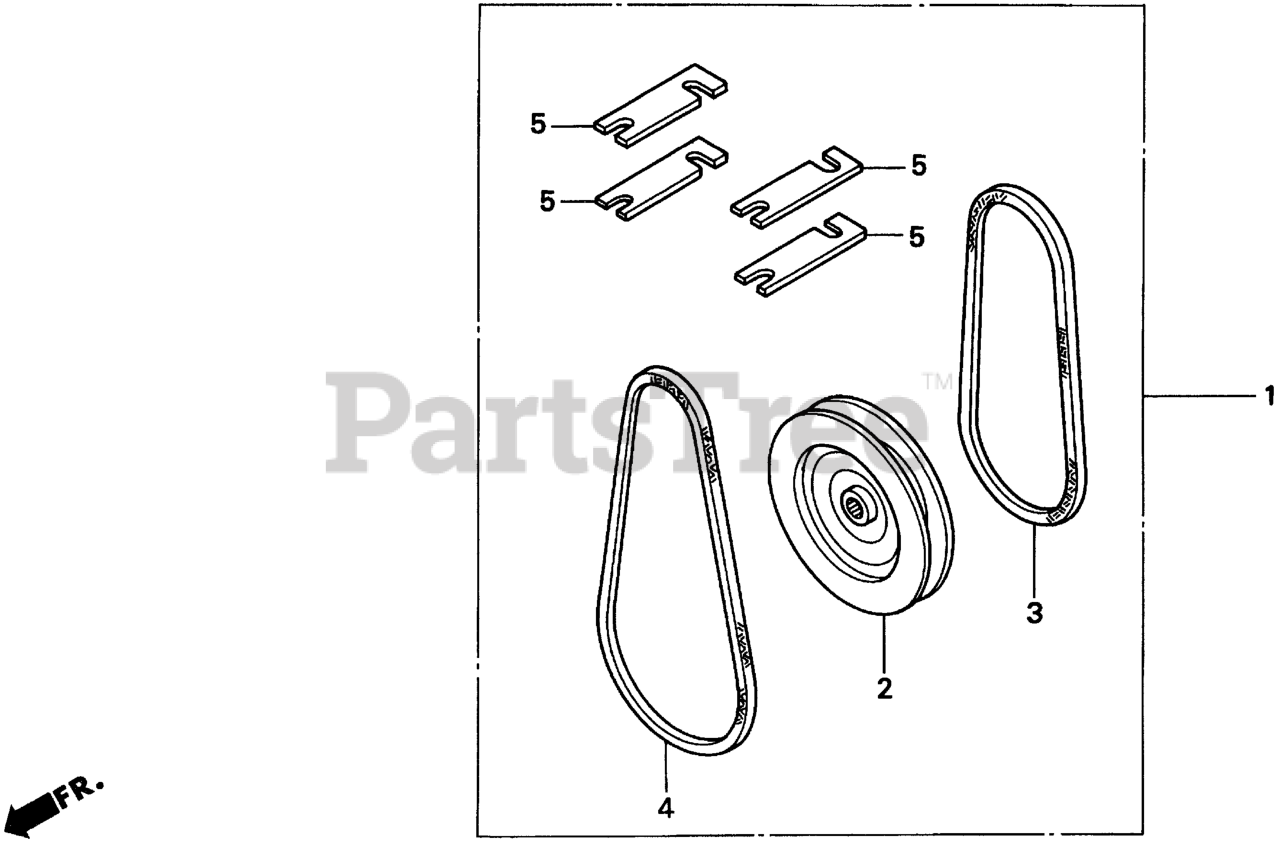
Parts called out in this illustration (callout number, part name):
1	BELT KIT
2	PULLEY, AUGER DRIVE
3	V-BELT (SA-31)
4	V-BELT (SB-32 R.E.C.)
5	SPACER, MOUNTING
